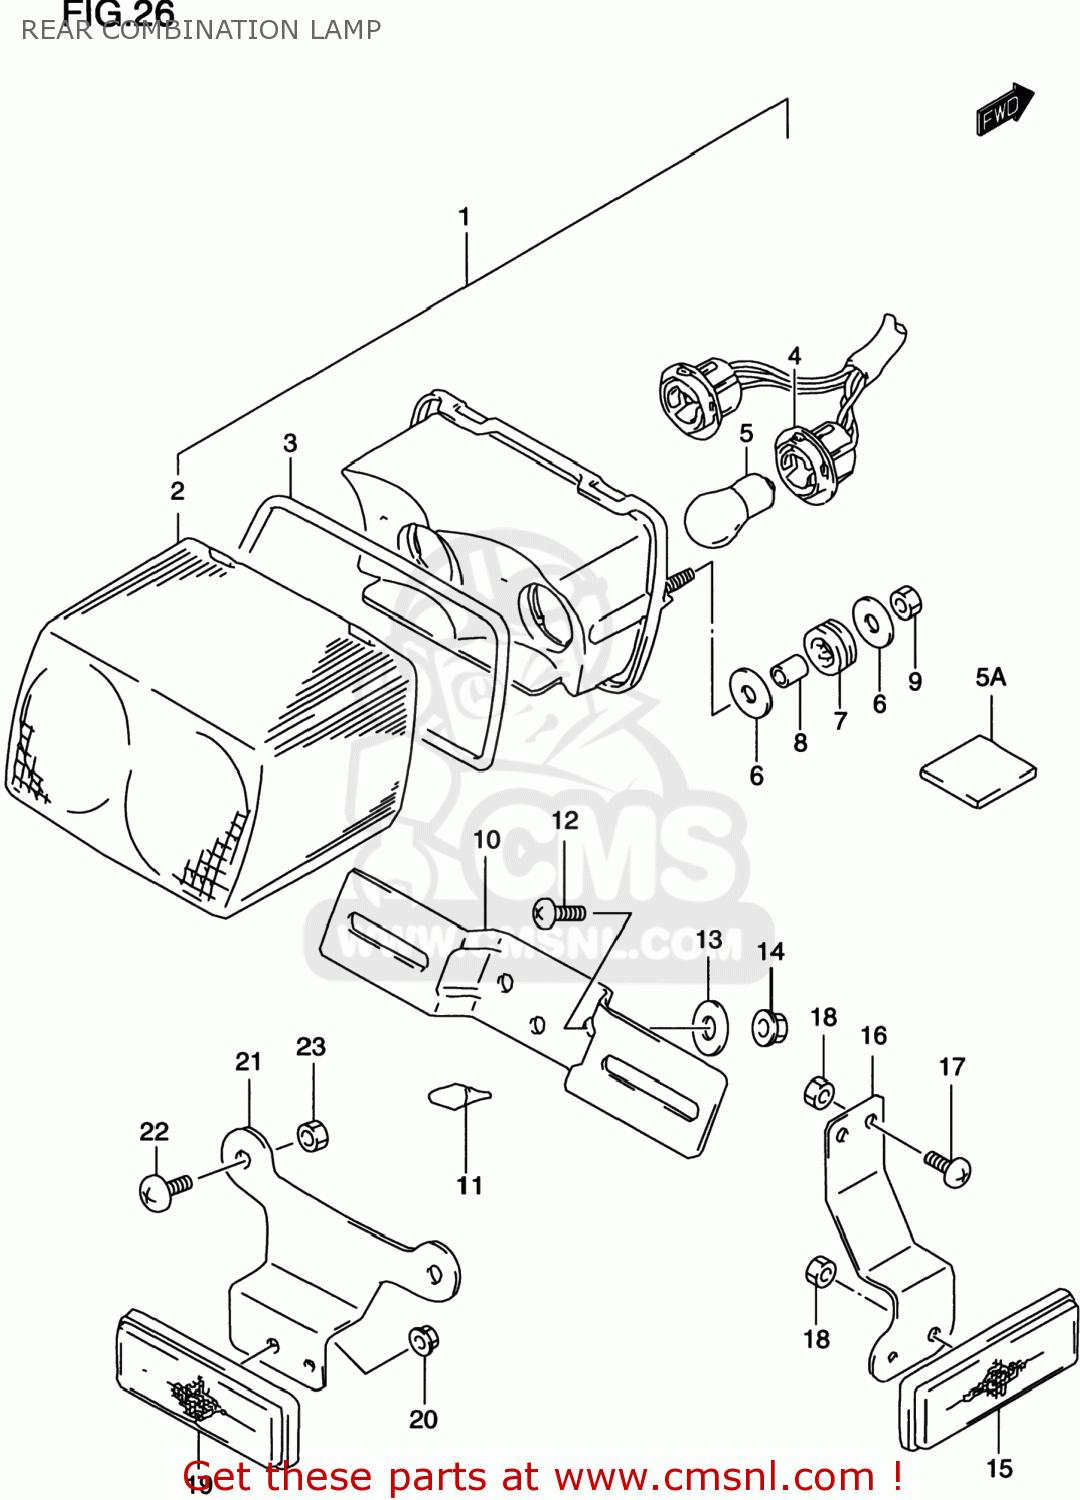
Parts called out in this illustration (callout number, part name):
1	LAMP ASSY,RR COMBINATION
2	LENS
3	GASKET (NAS)
4	SOCKET
5	BULB(12V21/5W)
5A	CUSHION,REAR LENS
6	WASHER(6.5X20X1.2)
7	CUSHION
8	SPACER(6.5X9X8.5)
9	NUT 6MM
10	BRACKET,LICENSE PLATE
11	CUSHION
12	SCREW
13	WASHER(6.5X20X1.2)
14	NUT 6MM
15	REFLECTOR ASSY,RR
16	BRACKET,RR SIDE REFLECTOR
17	SCREW 5X12
18	NUT
19	REFLECTOR ASSY,RR
20	NUT
21	BRACKET,RR RR
22	SCREW 6X12
23	NUT 6MM
